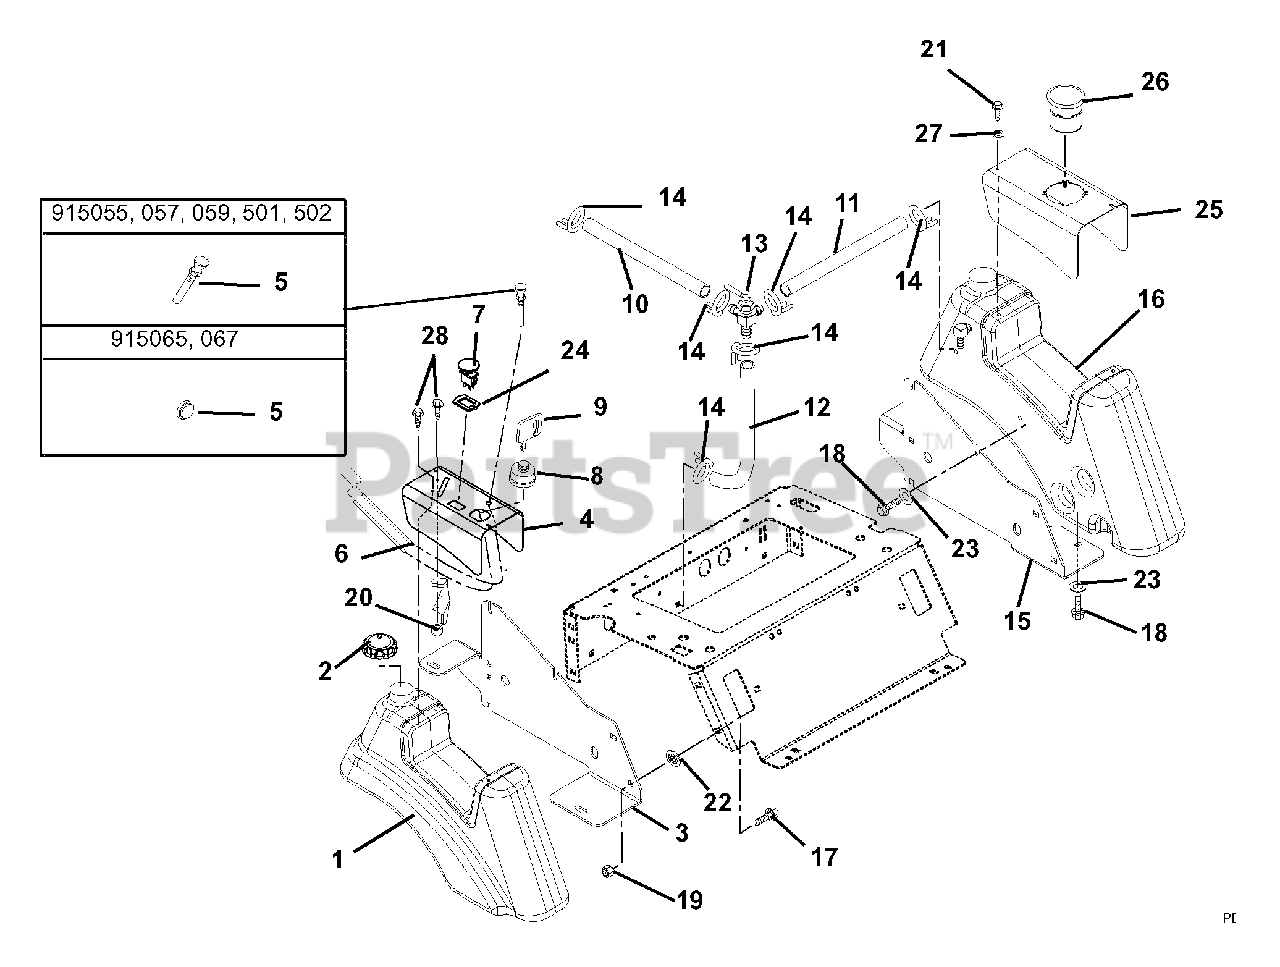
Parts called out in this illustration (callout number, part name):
1	FUEL TANK, RH
2	FUEL CAP
3	SEAT PLATE, RH
4	RH CONSOLE
5	CHOKE CABLE
6	THROTTLE CABLE
7	SWITCH, CLUTCH
8	KEY SWITCH
9	KEY -W/CAP
10	GAS LINE-BULK 1/4" I.D.
11	GAS LINE-BULK 1/4" I.D.
12	GAS LINE-BULK 1/4" I.D.
13	VALVE, FUEL
14	CLAMP-HOSE WIRE .490/.510X.116
15	SEAT PLATE, LH
16	FUEL TANK, LH
17	@BLT-RDHDSQNK .38-16X1.00 G5YZ
18	BLT-SERHFWH .312-18X.75 YWZC
19	@NUT-LK-NYL-FLG .38-16 YWZC
20	@NUT-LK-NYL 10-24 W/INSRT YWZC
21	SCR-MCH 10-24X3/8 SL HEX YWZC
22	RETAINER, .38 PUSH-ON
23	WSHR-FL-STL .328X1.0X.094 YWZC
24	SHIM,PTO SW (DELTA #972301)
25	LH CONSOLE
26	CUPHOLDER
27	WASHER, FENDER 3/16X3/4 YWZC
28	@SCR-MCH 10-24X.50 HWH YWZC
